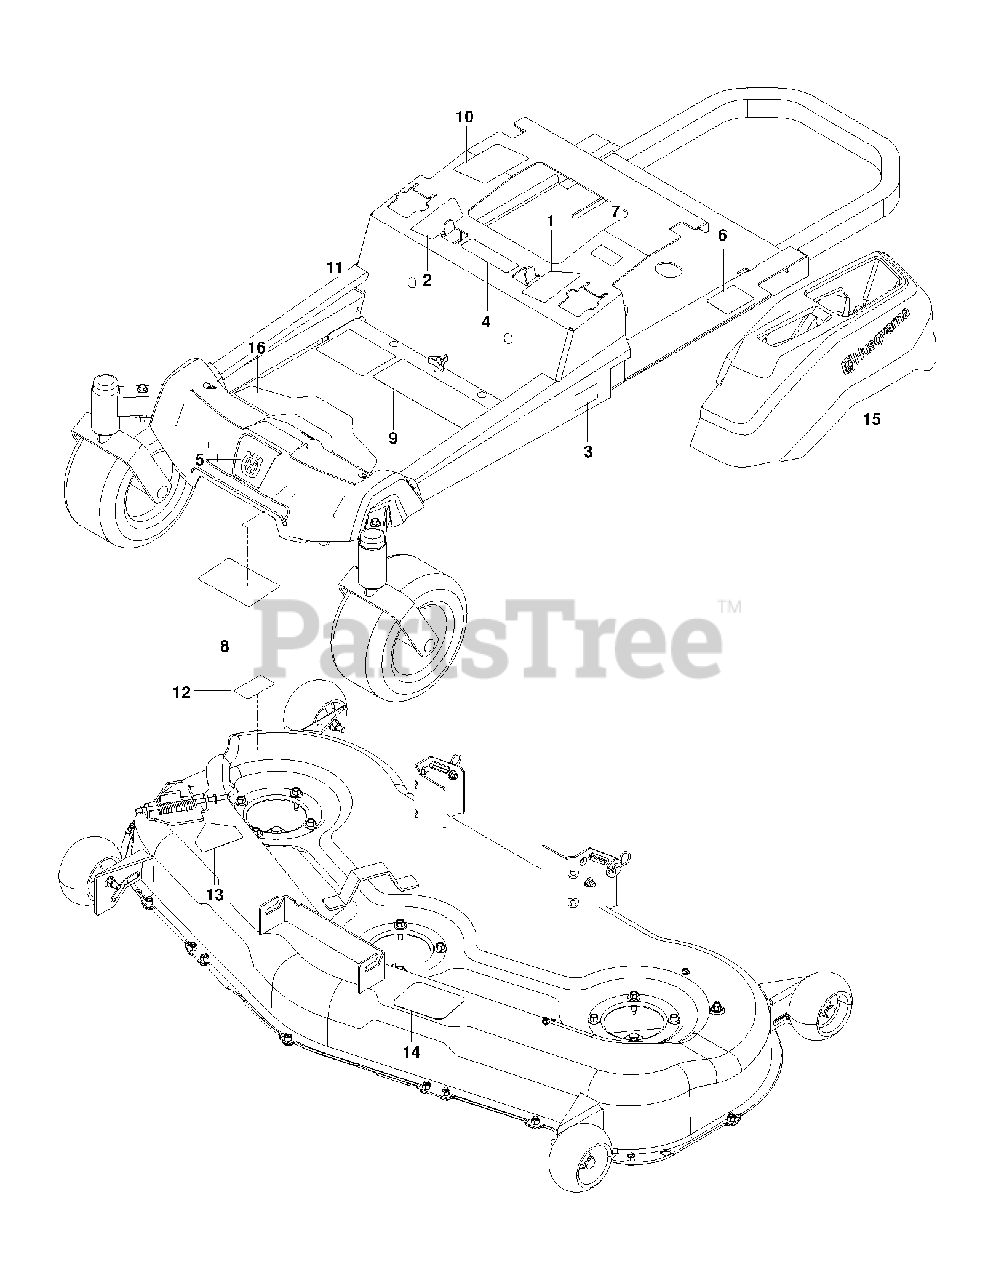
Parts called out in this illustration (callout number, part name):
1	DECAL.ZTR.RZ.THRTL/PRKBRK.V2.L
2	DECAL.ZTR.RZ.THRTL/PRKBRK.V2.R
3	DECAL.ZTR.SIDE.RAIL.GRAPHIC
4	EURO DECAL-BATTERY WARNIN6
5	DECAL.BADGE.55MM.CROWNH.HUSQ
6	DECAL, DO NOT TOW
7	DECAL, EXITING MOWER
8	DECAL, SERVICE
9	DECAL, SAFETY WARNING
10	DECAL.WARNING.CUST.RESP.E85.
11	DECAL.ZTR.STRTNGINST.REMOTECHK
12	DECAL.DECK.6MIL./DEF.SHLD.WARN
13	DECAL, DECK DEFLECTOR, WARNING
14	DECAL, BELT ROUTING
15	DECAL.HUSQVARNA.210MM
16	PAD.RZ.FOOTREST.PLATE
